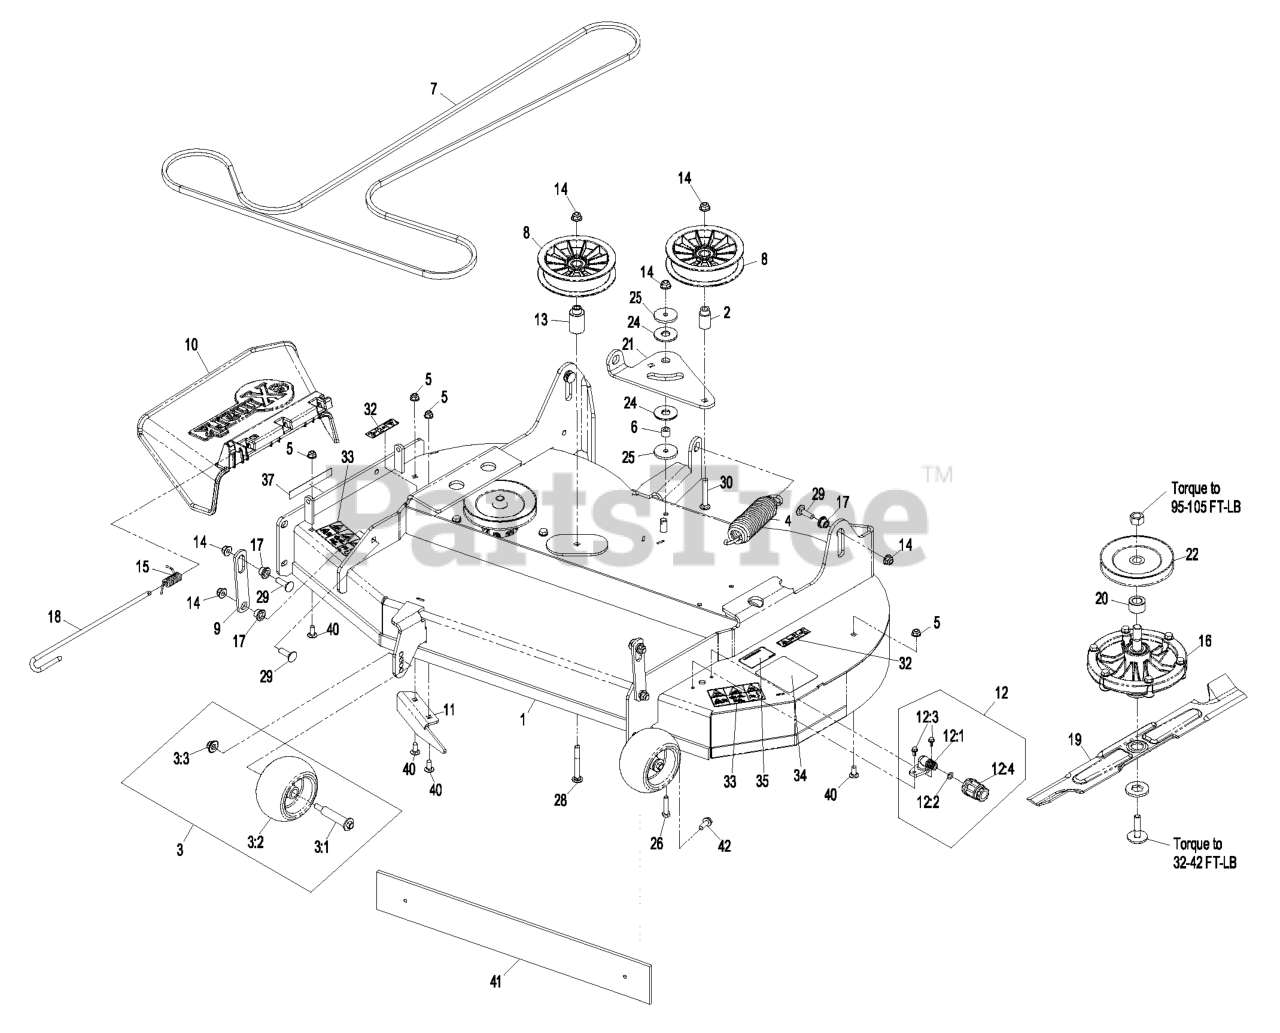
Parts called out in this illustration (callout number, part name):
1	ASM,DECK W/ DECALS
2	BUSHING-IDLER
3	ANTI-SCALP ROLLER KIT
3:1	BOLT-SHOULDER
3:2	ROLLER-SCALP, ANTI
3:3	NUT-HF, NI
5	NUT-HF, NI
6	BUSHING-LEVER, LIFT
7	BELT-V
8	PULLEY,IDLER 5"
9	HANGER-DECK
10	CHUTE DEFLECTOR XRK M056
11	BAFFLE-DISCHARGE
12	WASHOUT PORT KIT
12:3	SCREW-HWH
12:4	CONNECTOR-HOSE
13	BUSHING-IDLER
14	NUT-HF, NI
15	SPRING-TORSION
17	BUSHING-FLANGED
18	PIN-CHUTE
20	SPACER, DECK SHEAVE
21	Arm, Idler
24	WASHER-FRICTION, COMPOSIT
25	WASHER-PLAIN
26	SCREW-HH
28	BOLT-CARRIAGE
29	BOLT-CARR
30	SCREW-CARR
32	DECAL-WARNING, BELT SHIEL
33	DECAL-DANGER
34	DECAL-ROLLER, ANTI-SCALP
35	DECAL,BLADE TORQUE
37	DECAL-DANGER
40	SCREW-CARR
42	SCREW-TAPTITE
